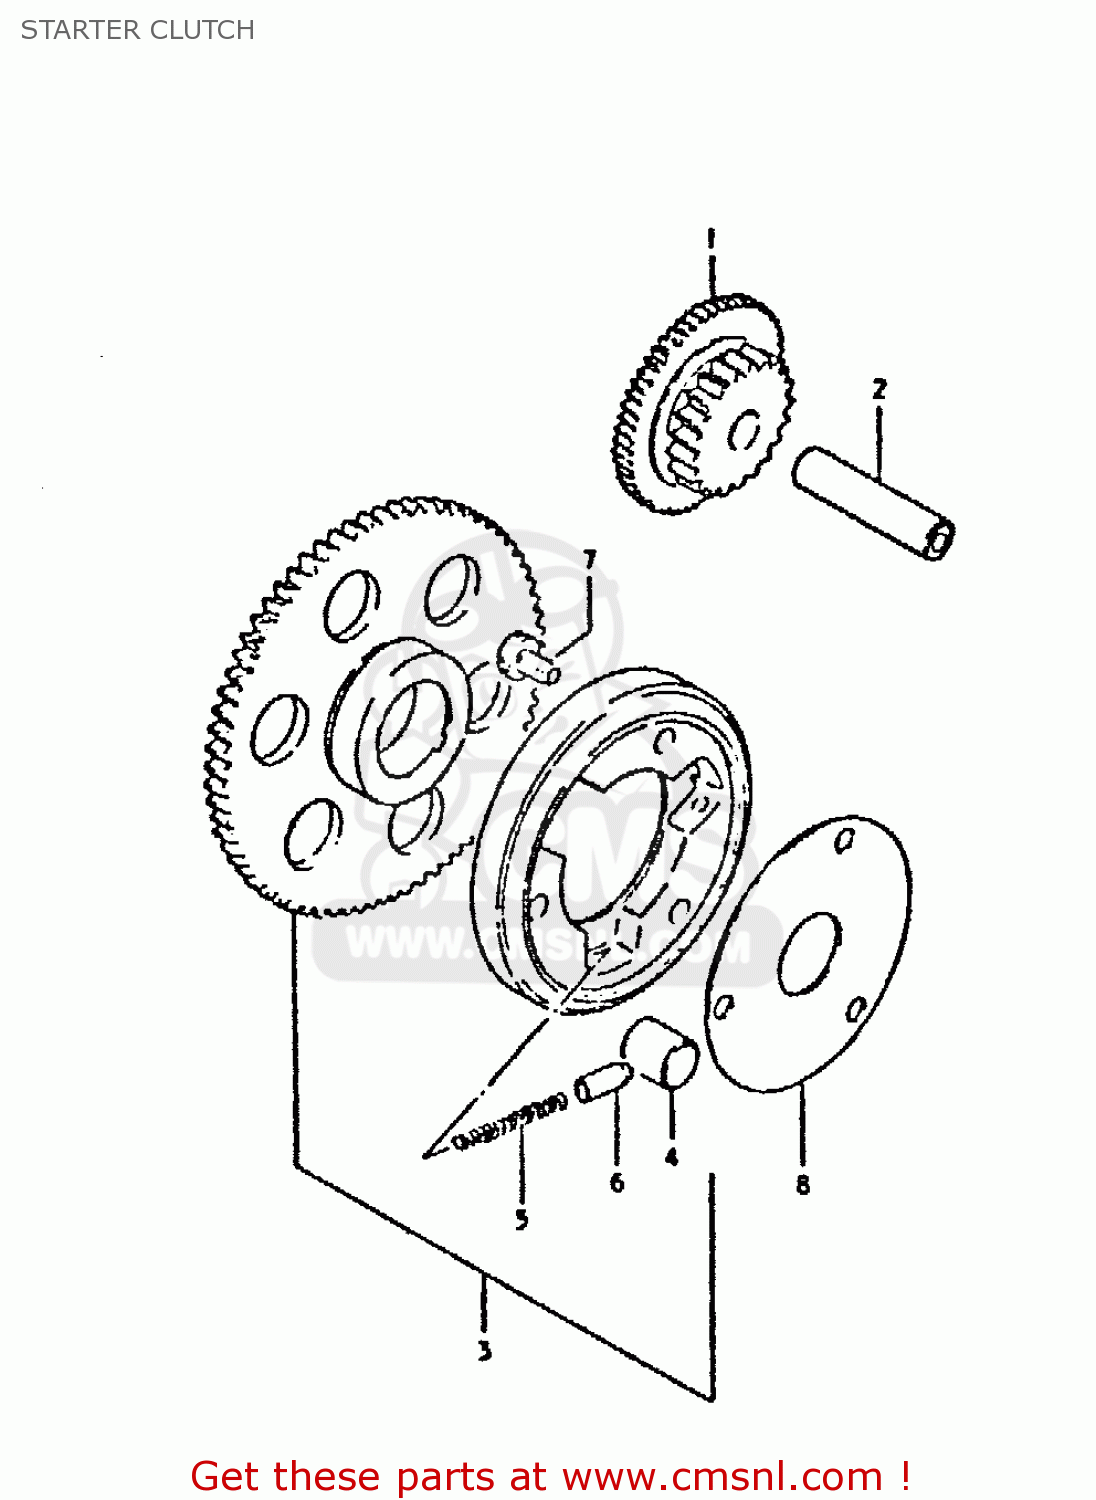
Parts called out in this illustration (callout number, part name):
1	GEAR,STARTER IDLE
2	PIN(7.4X13X56)
3	CLUTCH SET,STARTER
4	ROLLER(15X13)
5	SPRING
6	PIECE,PUSH
7	BOLT
8	SHIM,STARTER CLUTCH HUB
